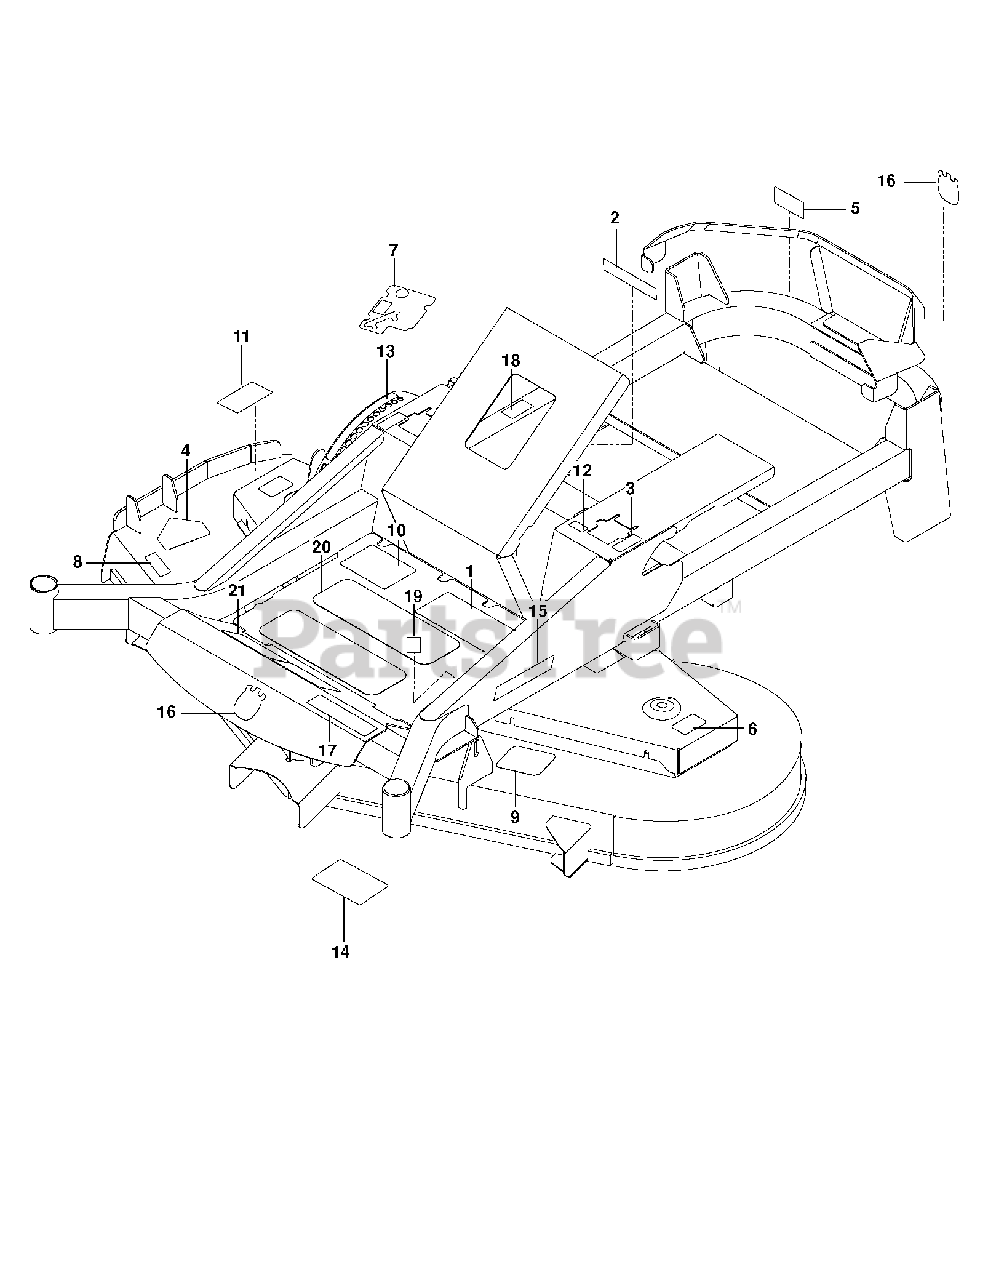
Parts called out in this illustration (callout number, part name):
1	DECAL, WARNING
2	EURO DECAL-BATTERY WARNIN6
3	DECAL, MOTION CONTROL
4	DECAL, CPSC
5	DECAL, BELT DRIVE
6	DECAL.DECK.6MIL.EURO.NOSTEP
7	DECAL ZTR CONTROL PANEL
8	DECAL, EURO SEVERING
9	DECAL, BELT ROUTING
10	DECAL ZTR STARTING
11	DECAL.DECK.6MIL./DEF.SHLD.WARN
12	DECAL, F.S.T.
13	DECAL, HEIGHT ADJUST
14	DECAL, SERVICE
15	RP.DECAL.BADGE.170MM.TEXTLOGO
16	DECAL.AUGER.HUSQ.CROWN.SNOW
17	DECAL.MZ52
18	DECAL, ECM, AUSTRALIA
19	DECAL.80.DBA.AUSTRALIA
20	ANTI-SKID PAD
